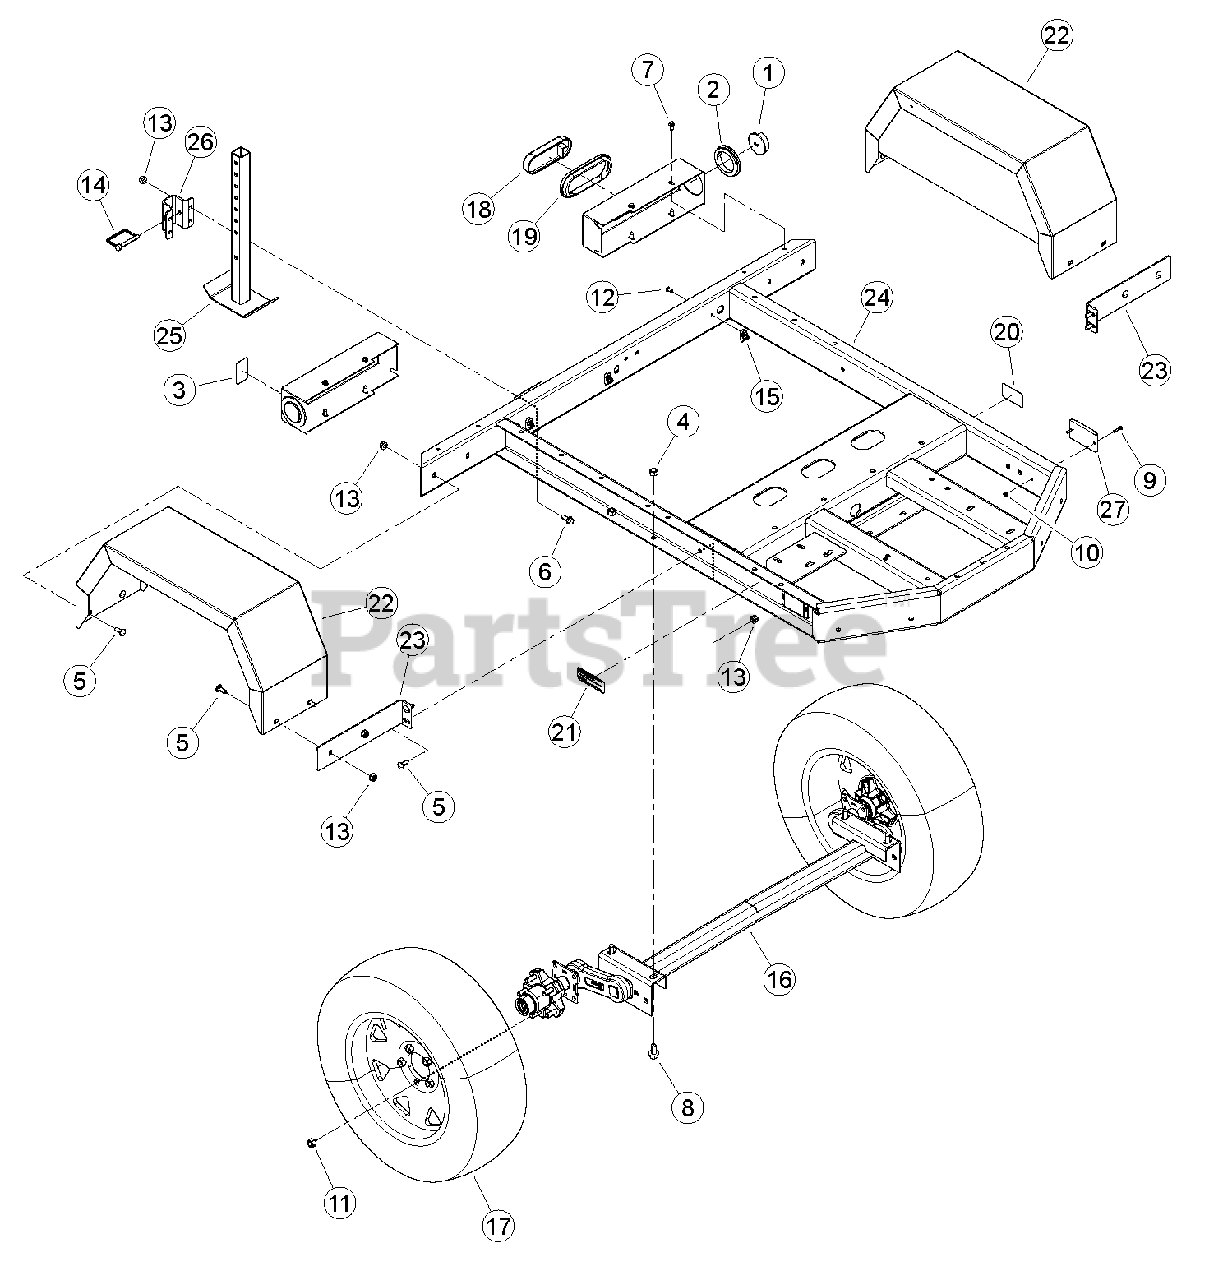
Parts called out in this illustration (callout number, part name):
1	LIGHT, RED CLEARANCE
2	GROMMET, CLEARANCE LIGHT
3	REFLECTOR, WIDE ANGLE RED
4	NUT, 1/2-13 GR5 CENTERLOCK GRB
5	BOLT, 3/8-16 X 1 GR5 CRG
6	BOLT, 3/8 X 1 FLANGE NC
7	SCREW, 11/32-12X7/8 HWH T-AB
8	BOLT, 1/2-13 1.00 GR5 FLANGE NC
9	SCREW, MCH 10-24 X 1" RND HD PHL ZP
10	NUT, 10/24 NYLOCK TYPE NM ZP
11	NUT, 1/2-20 WHEEL
12	RIVET, AL BLIND 1/4 X 3/4 DOME HEAD
13	NUT, 3/8-16 NYLOCK FLANGE
14	PIN, 3/8 X 2-1/2 LYNCH
15	CLAMP, CABLE MOUNT
16	AXLE, TORSION 1800
17	ASSEMBLY, TIRE AND WHEEL 14 IN
18	TAIL LIGHT, OVAL LED
19	GROMMET, OVAL TAIL LIGHT
20	DECAL, P205/75R14 LOAD RATING
21	DECAL, EPA EVAP
22	WELDMENT, 6" CHIPPER FENDER
23	BRACKET, 6" FENDER
24	WELDMENT, 6" CHIPPER TRAILER
25	WELDMENT, REAR STABILIZER
26	BRACKET, TAILLIGHT
27	KIT, LED AMBER LIGHT
